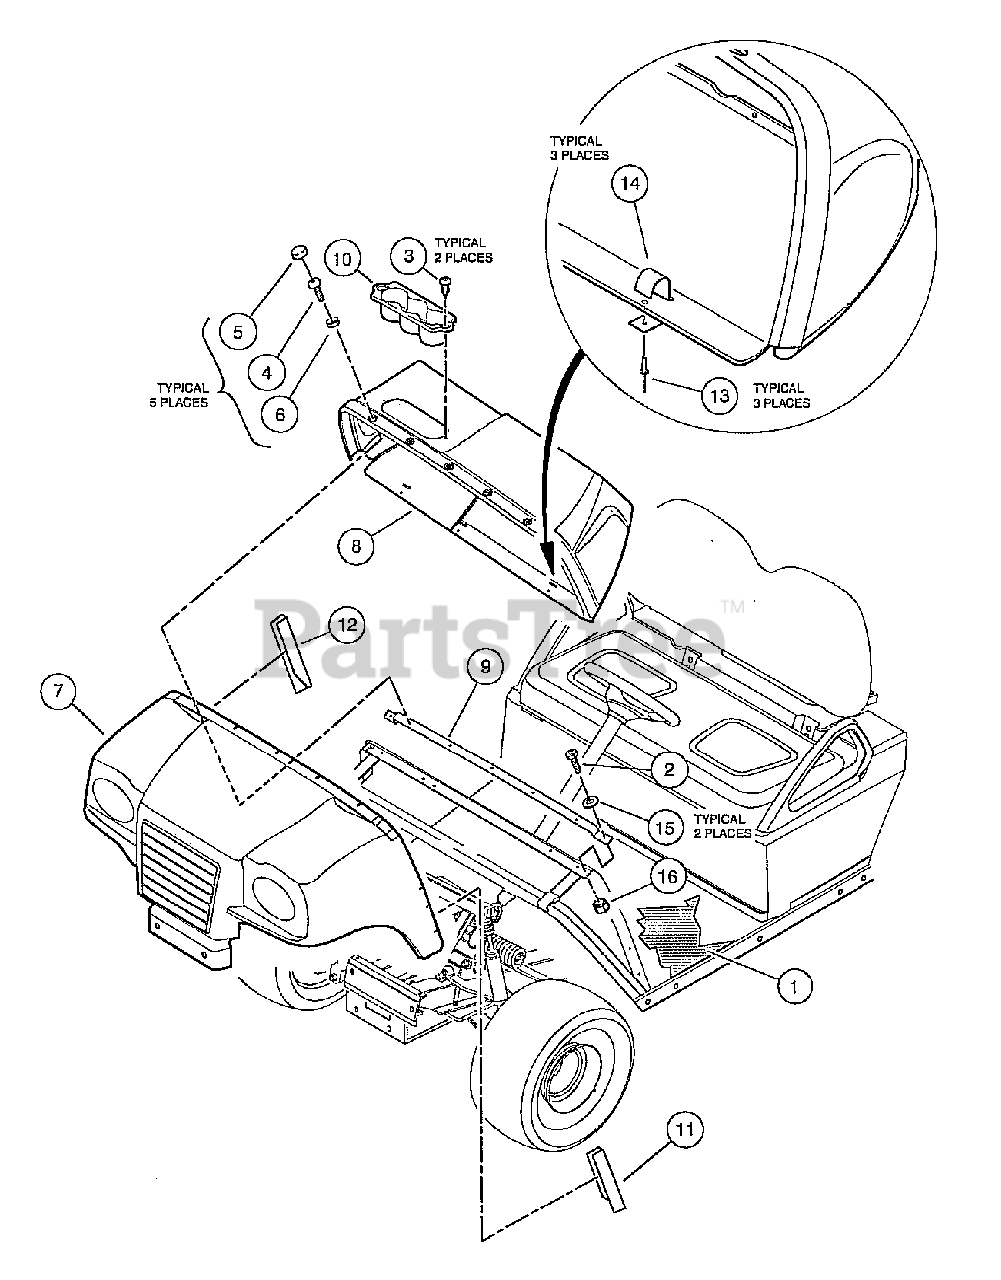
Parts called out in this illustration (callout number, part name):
1	Floormat
2	Screw, 1/4-20 X 0.75 Hex-Head
3	Screw, Tuflok Panel, 1/4
4	Screw, 1/4-20 X .75 Torx Pn Hd
5	Cap, 1/4" Plastic Screw Head
6	Washer, 1/4 ID Scalloped Plastic
7	Cowl, Orange
9	Support, Upper Cowl
10	Object Holder
11	Cowl Cover, Driver-Side
12	Cowl Cover, Passenger-Side
13	Rivet
14	Clip, Dash
15	Washer, 1/4 Type A Narrow Flat
16	Locknut, 1/4-20 Nylon Insert
